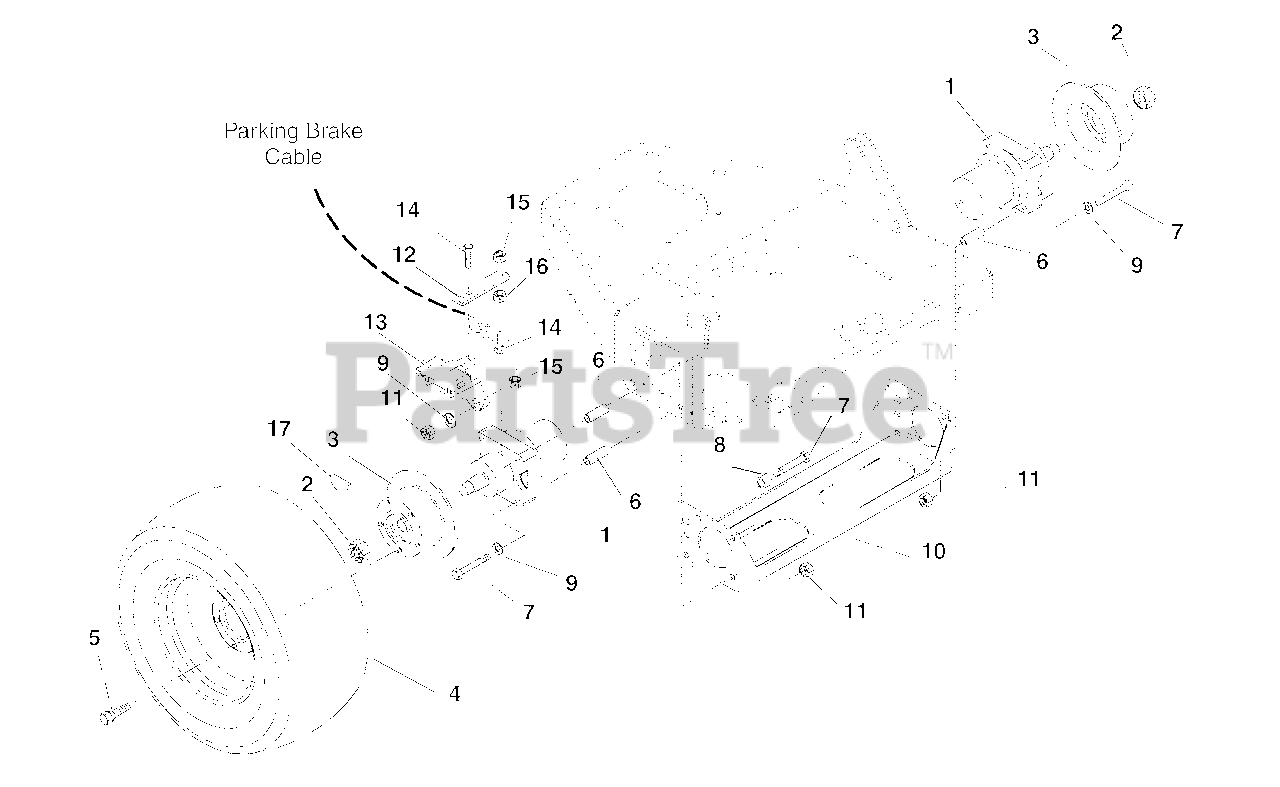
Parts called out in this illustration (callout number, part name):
1	Motor, Hydraulic Wheel
2	Nut, Locking-Jam-Patch 1.00-20
3	Hub and Disc
4	Wheel-Tire 23 x 10.50 - 12 Multi-Trac
5	Bolt-Lug .50-20 x 1.62
6	Bushing-Sleeve .513 x .748 x 2.129
7	Bolt-Hex .50-13 x 5.00 Grade 8
8	Spacer .50 x .75 x .32
9	Washer-Locking .50 x .125
10	Rod-Motor Connecting
11	Nut-Locking-Center .50-13
12	Arm, Extension Parking Brake
13	Caliper, Park Brake (Clockwise) Right Hand
13	Caliper, Park Brake (Counter Clockwise) Left Hand
14	Bolt-Hex .31-18 x 1.00 Grade 5
15	Nut-Locking-Nylon .31-18
16	Nut-Hex .31-18
17	Pad, Disk Brake
